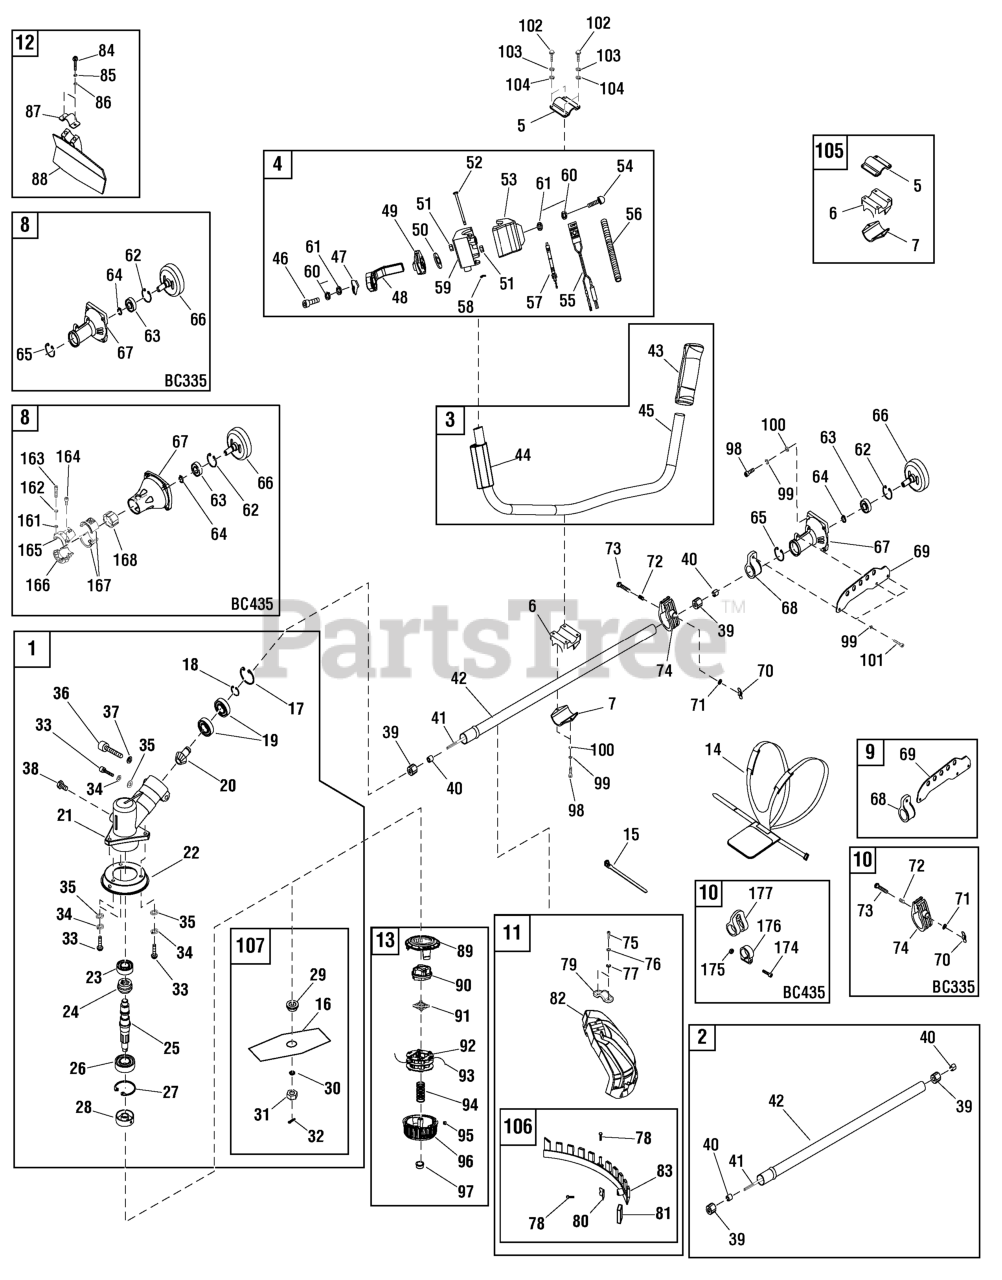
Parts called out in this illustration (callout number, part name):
1	KIT, Gear Box Assembly
2	KIT, Drive Shaft Assembly, BC335
2	KIT, Drive Shaft Assembly, BC435
3	KIT, Handle Assembly
4	KIT, Throttle Control Switch
5	CAP, Upper
6	BRACKET, Handle
7	CAP, Lower
8	KIT, Clutch Assembly, BC335
8	KIT, Clutch Assembly, BC435
9	KIT, Hang Ring, BC335
10	KIT, Ring for Limit, BC335
10	KIT, Ring for Limit, BC435
11	KIT, Guard Assembly
12	KIT, Safety Guard Assembly
13	KIT, Bump Head Assembly
14	SHOULDER HARNESS
15	BAND, Wire Clamp
20	PINION
21	GEAR BOX
22	COVER, Blade
23	BEARING
24	GEAR
25	SPLINE SHAFT
28	GASKET, Spline
29	HOLDER
30	WASHER, 10
32	SPLIT PIN
33	BOLT, M5 x 12
34	WASHER, Spring, 5
35	WASHER, Flat, 5
36	BOLT, M6 x 20
37	WASHER, Spring, 6
39	COVER, Rubber
40	BEARING, Oil
41	SHAFT, Drive
42	SHAFT, Straight, BC335
42	SHAFT, Straight, BC435
43	COVER, Handle, LH
44	COVER, Handle, RH, Rubber
45	HANDLE
46	BOLT, M5 x 16
47	WASHER, Wave
48	LEVER, Throttle
49	CONTROL BASE
50	SPACER, Plastic
52	SHAFT
53	CONTROL BOX, Up
54	BOLT, M5 x 20
55	STOP BUTTON, Complete
56	TUBE
57	CABLE, Complete
59	CONTROL BOX, Down
60	WASHER, Spring, 5
61	WASHER, Flat, 5
66	CLUTCH DRUM, Complete
67	CASE, Clutch, BC435
68	RING, Hang
69	HANDLE, Hang
72	SPRING
74	RING FOR LIMIT
75	SCREW, M5 x16
76	WASHER, Spring, 5
77	WASHER, Flat, 5
78	SCREW, Self Tapping, ST4.2 x 16
79	BRACKET, Safety Guard
81	COVER, Blade
82	SAFETY GUARD
83	SECURING SADDLE
84	BOLT, M6 x 20
85	WASHER, Spring, 6
86	WASHER, Flat, 6
87	HOLDER
88	SAFETY GUARD
89	COVER, Bump Head
90	BUMP HEAD
91	COVER, Rope
92	SEAT, Rope
93	ROPE
94	SPRING, Bump Head
95	COVER, Rope
96	BOX, Bump Head
97	NUT
98	BOLT, M6 x 20
99	WASHER, Spring, 6
100	WASHER, Flat, 6
101	SCREW, M6 x 16
102	SCREW, M5 x 16
103	WASHER, Spring, 5
104	WASHER, Flat, 5
105	KIT, Handle Bracket Assembly
106	KIT, Securing Saddle Assembly
107	KIT, Blade Assembly
161	WASHER, Flat, 5
162	WASHER, Spring, 5
163	BOLT, M5 x 20
164	BOLT, M5 x 10
165	SEMICIRCULAR BOARD A
166	SEMICIRCULAR BOARD B
167	BOOT, Rubber, A
168	BOOT, Rubber, B
174	BOLT, M5 x 20
175	NUT, M5
176	RING FOR LIMIT, 28
177	HANG RING, 28
